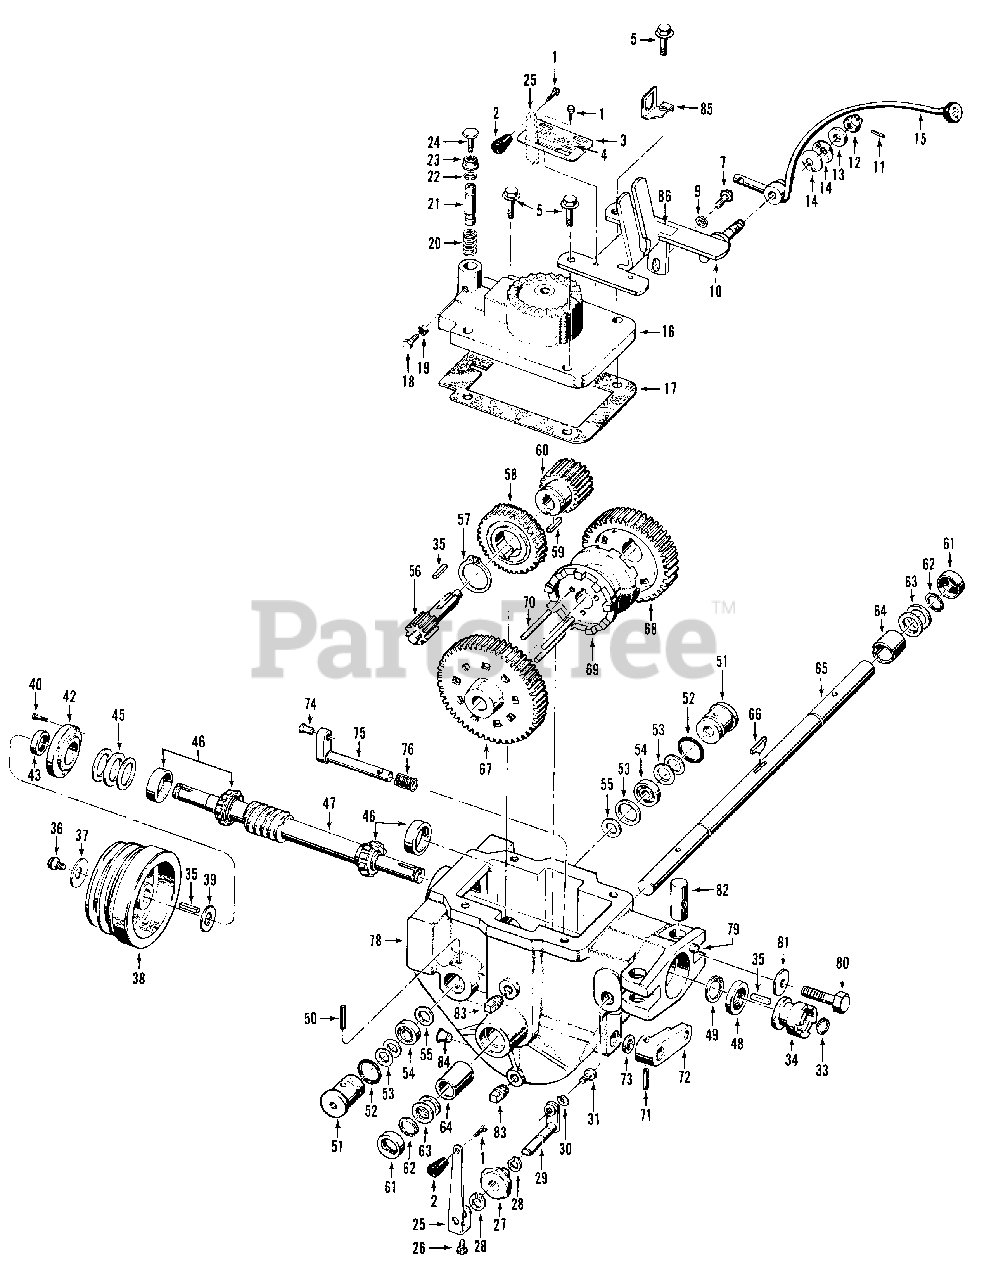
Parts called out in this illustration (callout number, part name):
1	Bolt-hex hd., #10-32 x 3/8 self-locking flange
2	Knob-tines/PTO clutch lever, tapered, plastic tapered, plastic
3	Detent Plate- tines / PTO clutch lever
4	Decal-operating instructions, detent plate
5	Bolt-flanged hex hd., 3/8-16 x 1-1/2"
7	Bolt-flanged hex hd., 5/16-18 x 3/4 Grade 5
9	Washer-flat, 5/16",
10	Bracket-shift levers
11	Pin-spring, 1/8"
12	Nut-castle (slotted) 1/2"-20
13	Washer-shoulder, 1/2"
14	Washer-disc spring
15	Lever-wheel speed shift
16	Cover-power unit transmission
17	Gasket-transmission cover
18	Bolt-hex hd., 5/16-18 x 1, Grade 5
19	Nut-hex, 5/16"-18
20	Spring-neutral plunger
21	Plunger-neutral
22	Clip Ring-retains neutral plunger
23	Nut-hex, flange locknut, 3/8"-16
24	Bolt-hex hd., 3/8-16x1-1/2" threaded full length
25	Lever-eccentric, tines/PTO clutch lever eccentric shaft
26	Bolt-hex hd., 1/4-20 x 1/2"
27	Bushing-tines/PTO clutch lever eccentric shaft
28	Retaining Ring-(snap ring) external
29	Eccentric-shaft, tines/PTO lever
30	Lockwasher-hi-collar, 1/4"
31	Screw-socket hd., 1/4-20 x 3/8"
33	Retaining Ring-external
34	Dog Clutch-power unit
35	Key-3/16 sq x 1"
36	Bolt-hex hd., 5/16-24 locking flange, Grade 5
37	Washer-disc spring
38	Pulley-transmission drive,
39	Washer-flat, hardened shoulder 1-1/4"
40	Bolt-hex hd., 1/4-20 x 3/4", front bearing camp
42	Cap-front bearing
43	Seal-oil, front bearing cap
45	Shim-front bearing cap, 010thich
45	Shim-as above, 030"
45	Shim-as above, 005"
45	Shim-as above, 062"
46	Bearing & Race (incl. 1 bearing GW-9400 & 1 cup (race) GW-9401
47	Shaft-main drive, power unit
48	Seal-oil, drive shaft, rear
49	Retaining Ring-(snap ring), internal
50	Pin-roll (spiral), 1/4 x 2
51	Plug-retaining, pinion bearing
52	O-Ring-retaining plug
53	Shim-retaining plug, 1-164" inner dia., .033 thick )
53	Shim-same as GW-1132-1, .062"
53	Shim-same as GW-1132-1, .010"
54	Bearing-ball, pinion shaft
55	Washer-pinion shaft
56	Stem Pinion-slow speed gear and shaft
57	Ring-retaining, external
58	Worm Gear-bronze, wheel drive
59	Key-3/16" x 5/8"
60	Gear-fast speed pinion
61	Seal-oil, wheel shaft
62	Retaining ring-external
63	Shim-wheel shaft, 1-1/64" inner dia., .062 thick
63	Shim-as above, .030" thick
63	Shim-as above, .015" thick
63	Shim-as above, .010" thick
63	Shim-as above, .005 thick
64	Bushing-bronze, bearing
65	Shaft-wheel, 15-5/8"
66	Key-Hi Pro, 1/4"
67	Gear-slow speed, wheel
68	Gear-fast speed,
69	Dog Clutch-wheel
70	Pin-clutch guide, 1/4" diameter
71	Pin-roll, 3/16" x 1-1/4"
73	Seal-oil, eccentric shaft
74	Pin-eccentric shaft, wheel speed shifting
75	Eccentric Shaft-wheel speed shifting
76	Spring-eccentric shaft
78	Housing-power unit transmission
79	Pin-alignment
80	Bolt-hex hd., 1/2-13 x 2 Gr5
81	Washer-disc spring (concave) domed side faces bolt head)
82	Post-with threaded hole for Ref. No. 80
83	Plug-pipe, 1/4"
84	Plug-red plastic, thread protector
85	Clip-forward interlock system plug connector
86	Decal-forward interlock wire harness
